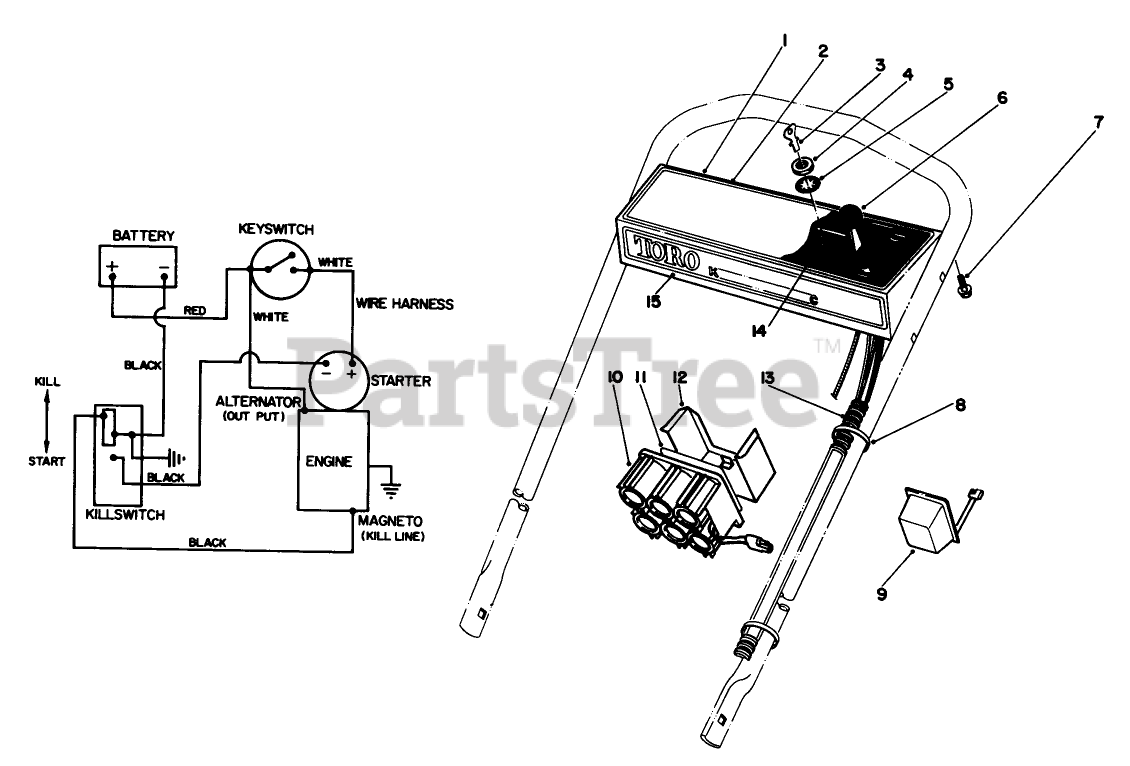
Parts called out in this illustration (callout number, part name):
4	NUT-HH
5	Lockwasher
6	SERVICE THROTTLE CONTRO
7	SCREW-HWHTF
8	TIE-CABLE
10	BATTERY ASSEMBLY,WET
13	WIRE HARNESS
14	STARTER SWITCH ASM
